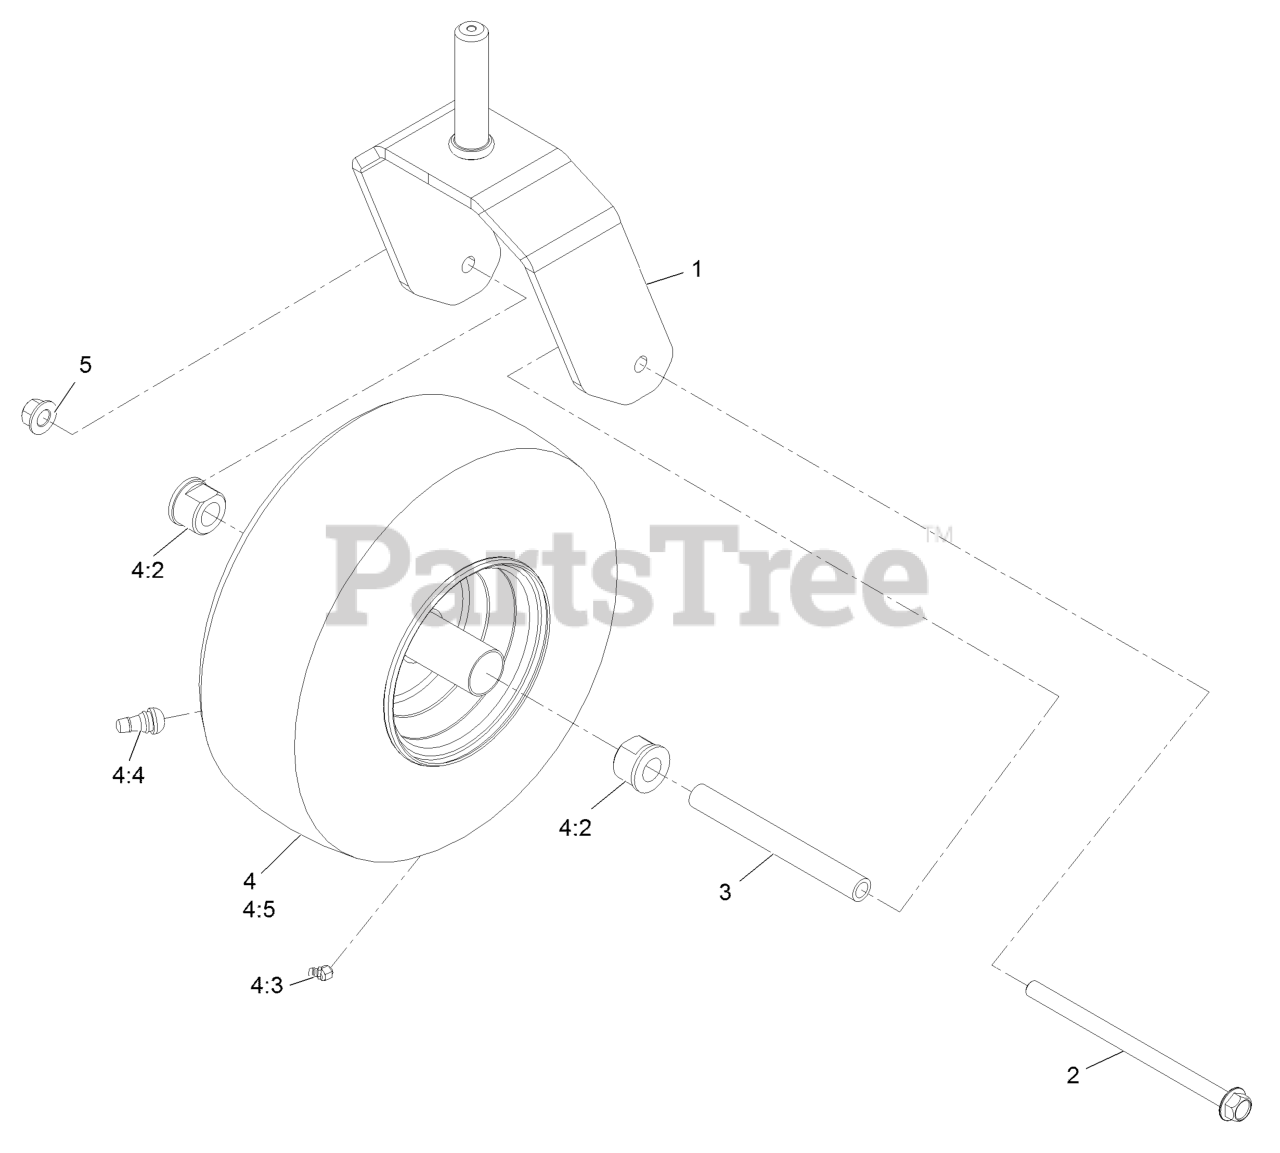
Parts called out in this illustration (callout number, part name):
1	Fork-Caster
2	Screw-HHF
3	Spanner-Wheel, Caster
4	ASM, Tire & Wheel
4:2	Bushing-Flange
4:3	Fitting-Zerk
4:4	Valve
5	Nut-Lock 1/2-13
